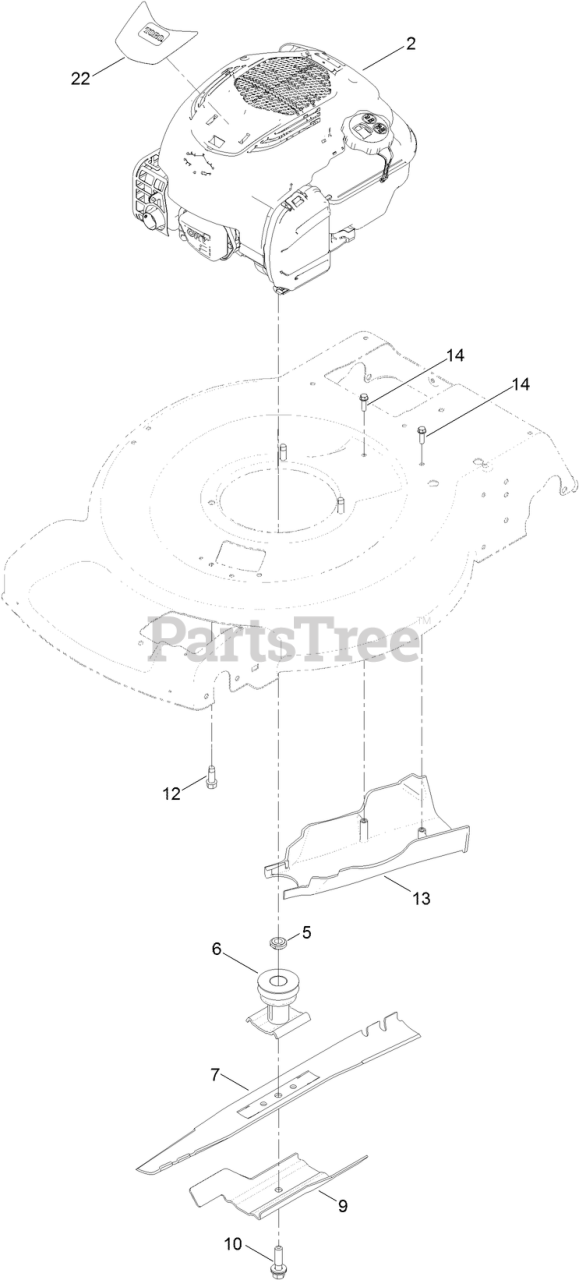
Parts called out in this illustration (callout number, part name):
5	Spacer-Driver
6	DRIVER-BLADE
9	Accelerator-Blade
10	BOLT-BLADE
11	GUIDE-BELT
12	SCREW-TAPTITE
13	COVER-BELT, REAR
14	SCREW-HWH
22	DECAL-SHROUD
